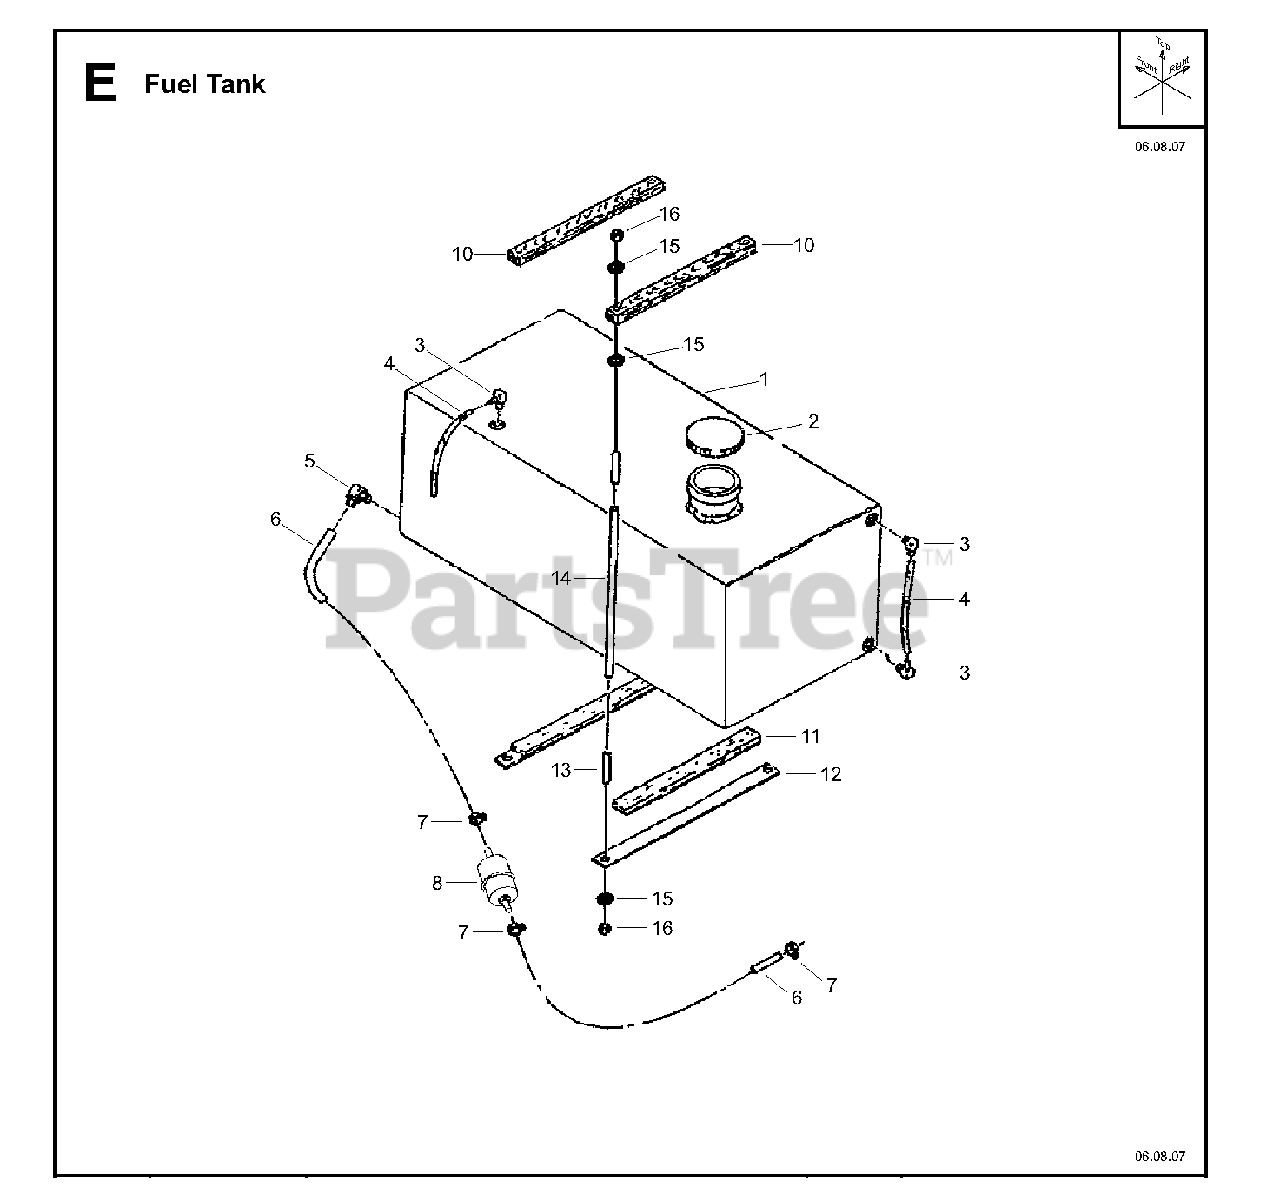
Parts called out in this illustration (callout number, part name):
6	CLAMP, HOSE, MAH-4 FUEL LINE
15	WASHER
16	NUT
